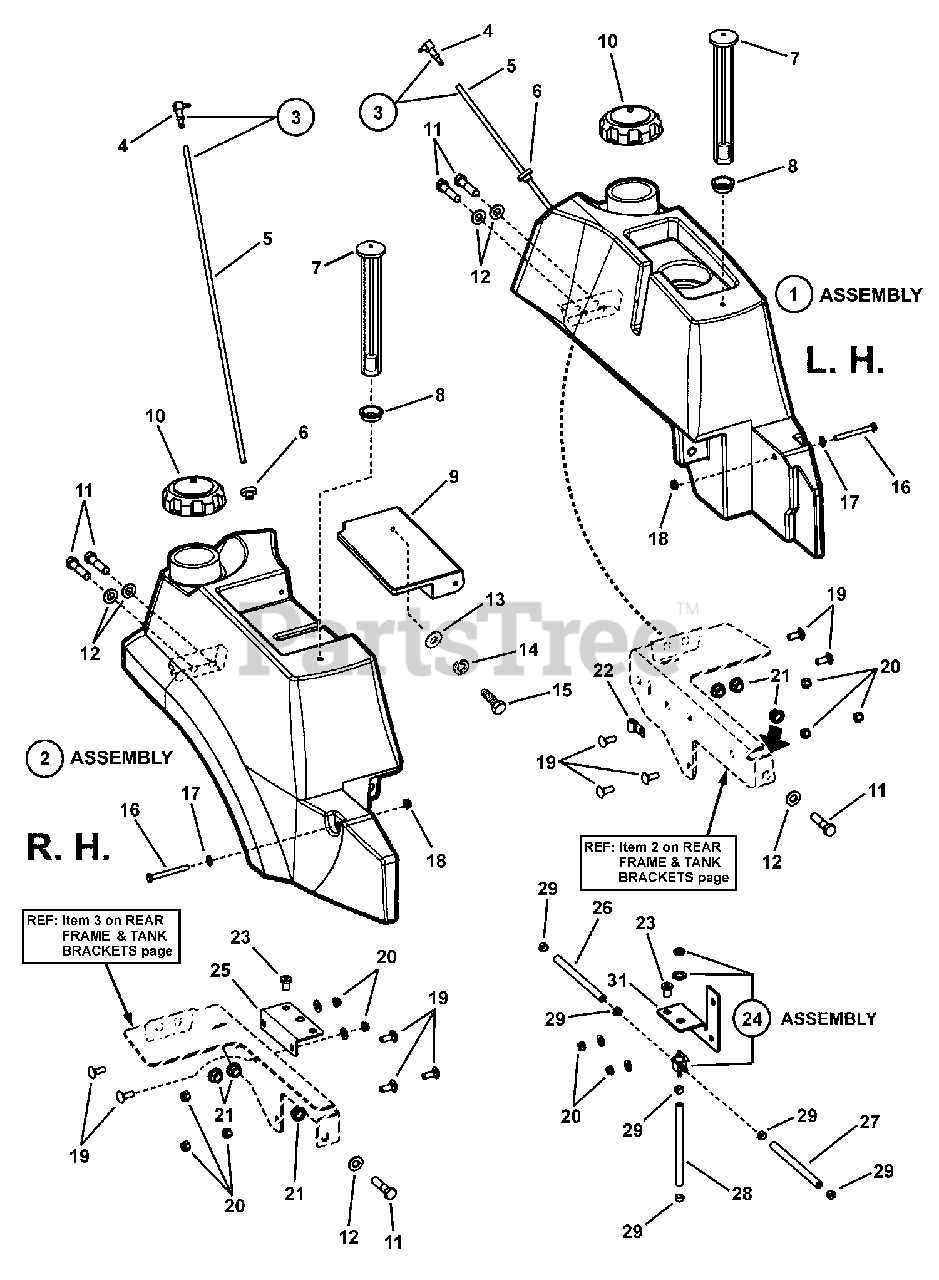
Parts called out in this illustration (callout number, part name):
1	ASSEMBLY, LH Fuel Tank
2	ASSEMBLY, RH Fuel Tank
3	ASSEMBLY, Fuel Pickup
4	ELBOW, 90 Degree
5	TUBE, Pickup
6	GROMMET, Tube
7	GAGE, Fuel
8	GROMMET, Gage
9	LID, Fuel Tank
10	CAP, 3-1/2" Fuel
11	SCREW, 7/16-14 x 2" Hex Head Cap, GR 5
12	WASHER, 1/2" Flat SAE
13	WASHER, 1/4" Flat
14	WASHER, 1/4" Split Lock
15	SCREW, 1/4-20 x 1-1/4" Hex Head Cap, GR 5
16	SCREW, 5/16-18 x 2-1/2" Hex Head Cap, GR 5
17	WASHER, 5/16" Flat
18	NUT, 5/16-18 Hex Nyloc
19	BOLT, 3/8-16 x 1" Square Neck Carriage, GR 5
20	NUT, 3/8-16 Hex Nyloc
21	NUT, 7/16-14 Hex Nyloc
22	CLIP, Open 3/8" Cushioned
23	WELL-NUT, 1/4-20 x 53/64
24	ASSEMBLY, 3-Way Fuel Valve
25	BRACKET, RH
26	HOSE, 1/4" I.D. x 1'-8" Long Fuel (L.H.)
27	HOSE, 1/4" I.D. x 3'-7.5" Long Fuel (R.H.)
28	HOSE, 1/4" I.D. x 1' Long Fuel
28	HOSE, 1/4" I.D. x 1'-9" Long Fuel
29	CLAMP, Fuel Hose
31	BRACKET, Seat Belt, LH
